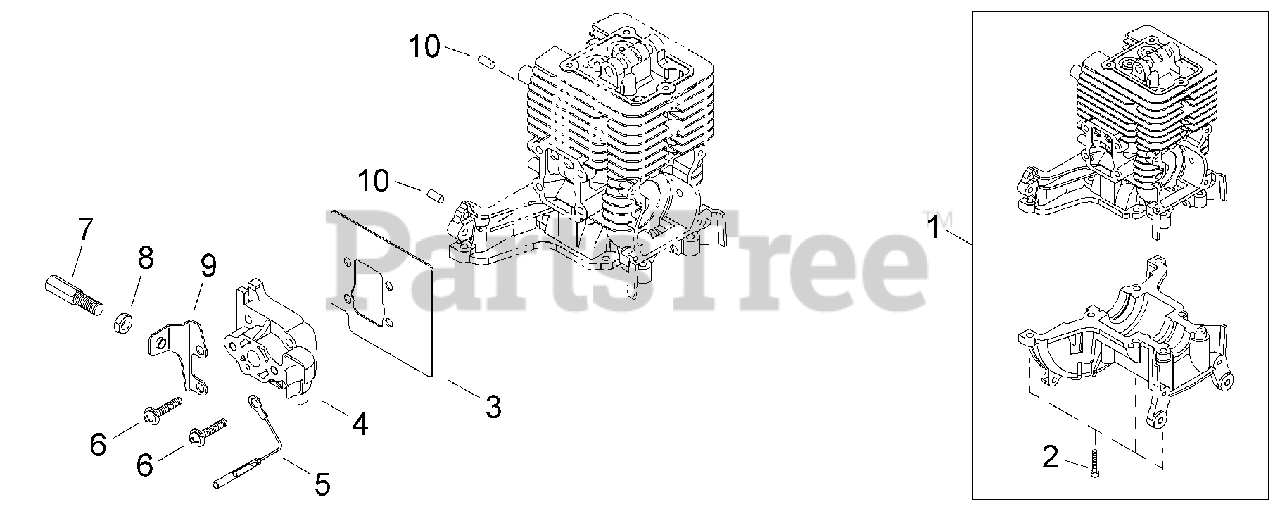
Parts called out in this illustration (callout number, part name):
1	CYLINDER BLOCK SET
2	SCREW - 5X16
3	DEFLECTOR, HEAT
4	VALVE, REED
5	LEAD - GROUND
6	SCREW - 5X25
7	NUT, CABLE ADJUST
8	LOCKNUT - 6
9	BRACKET, THROTTLE CABLE
10	PIN - LOCATING
